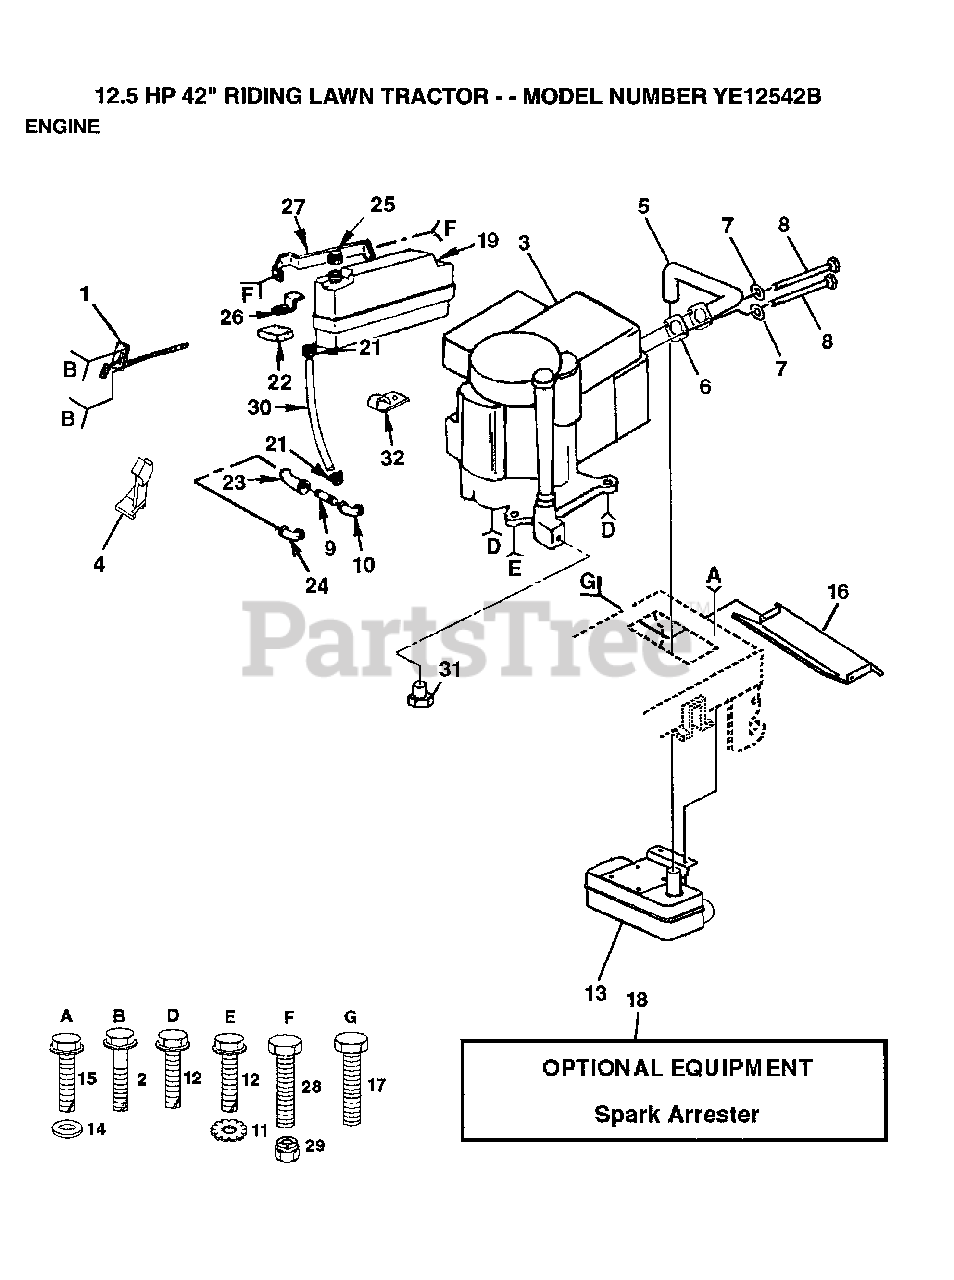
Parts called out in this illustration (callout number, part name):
1	THROTTLE CONTROL
2	SCREW LT
5	PIPE EXHAUST
7	LOCKWASHER
8	SCREW LT
9	PIPE NIPPLE
10	STREET ELBOW LT
11	LOCKWASHER
12	SCREW
13	MUFFLER EUROPE
14	WASHER
15	SCREW
16	HEAT SHIELD
17	SCREW
19	FUEL TANK
21	HOSE CLAMP
22	PAD-SPACER T
23	STREET ELBOW LT
24	ELBOW
26	BRACE-TANK LT
27	SUPT TANK FUEL
28	BOLT
30	HOSE T
32	CLIP T
